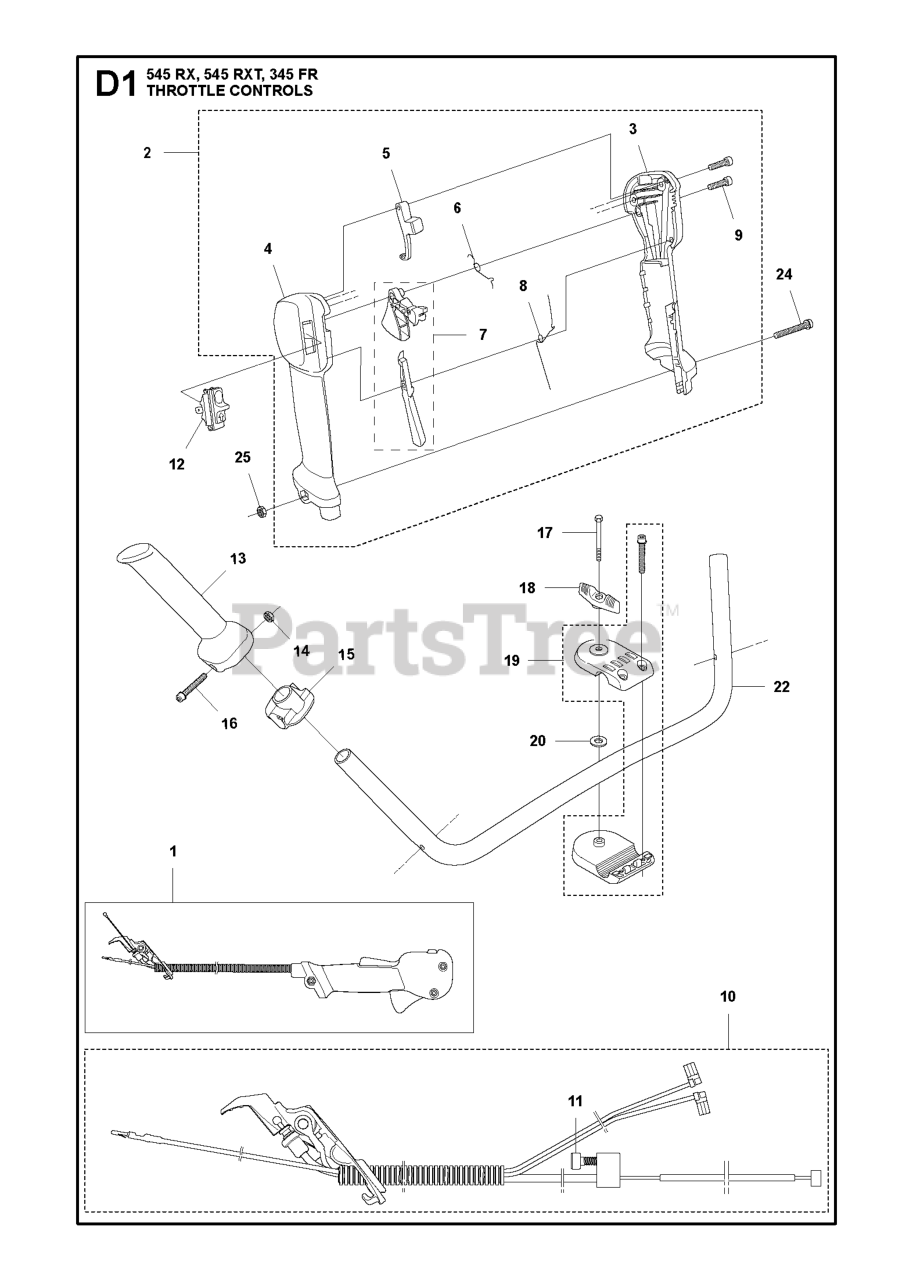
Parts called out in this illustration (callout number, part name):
1	THROTTLE HANDLE ASSY
2	THROTTLE HANDLE ASSY
3	HANDLE HALF RIGHT
4	HANDLE HALF LEFT
5	LOCKOUT STARTER THROTTLE
7	THROTTLE CONTROL
10	WIRING ASSY
11	SCREW
12	STOP BUTTON
14	NUT M6M M5
19	HANDLEBAR BRACKET KIT
19	HANDLEBAR BRACKET SPARE PART K
24	SCREW
